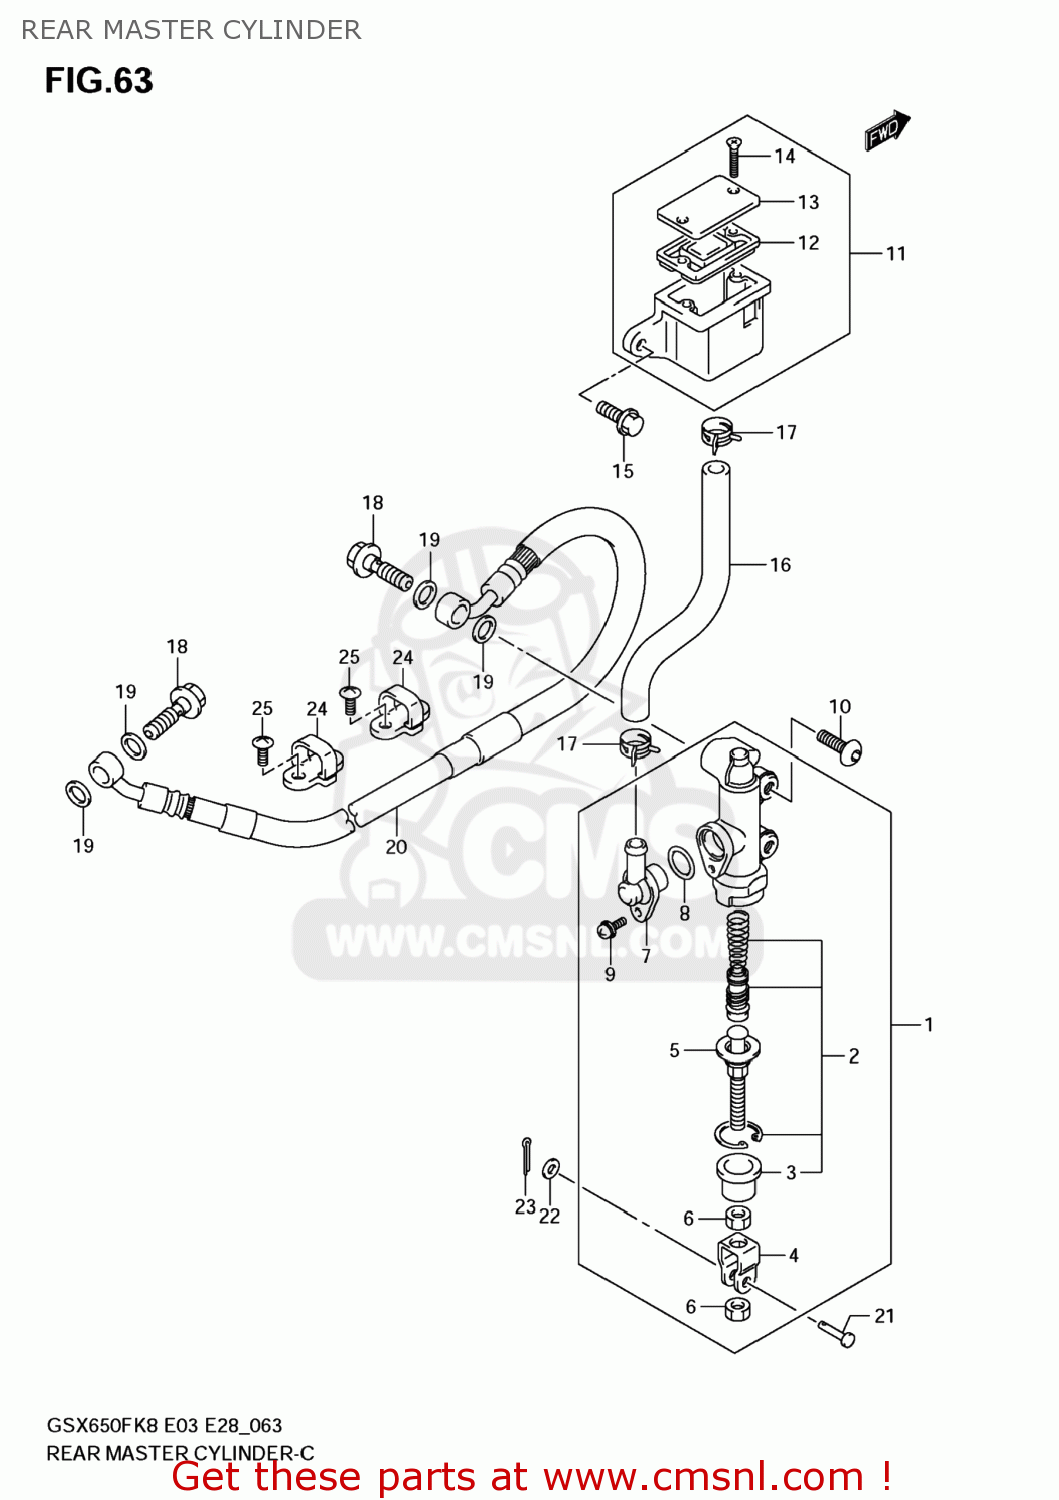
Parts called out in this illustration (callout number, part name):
1	CYLINDER ASSY,RR MASTER
2	PISTON/CUP SET
3	BOOT
4	YOKE
5	ROD,PUSH
6	NUT
7	CONNECTOR
8	O RING
9	SCREW
10	BOLT(8X20)
11	TANK ASSY,RESERVOIR
12	DIAPHRAGM
13	CAP
14	SCREW
15	BOLT
16	HOSE,RR RESERVOIR TANK
17	CLIP
18	BOLT UNION
19	WASHER(10X15X1.5)
20	HOSE,RR BRAKE
21	PIN(6X18.2)
22	WASHER
23	PIN
24	GUIDE,RR BRAKE HOSE
25	SCREW
